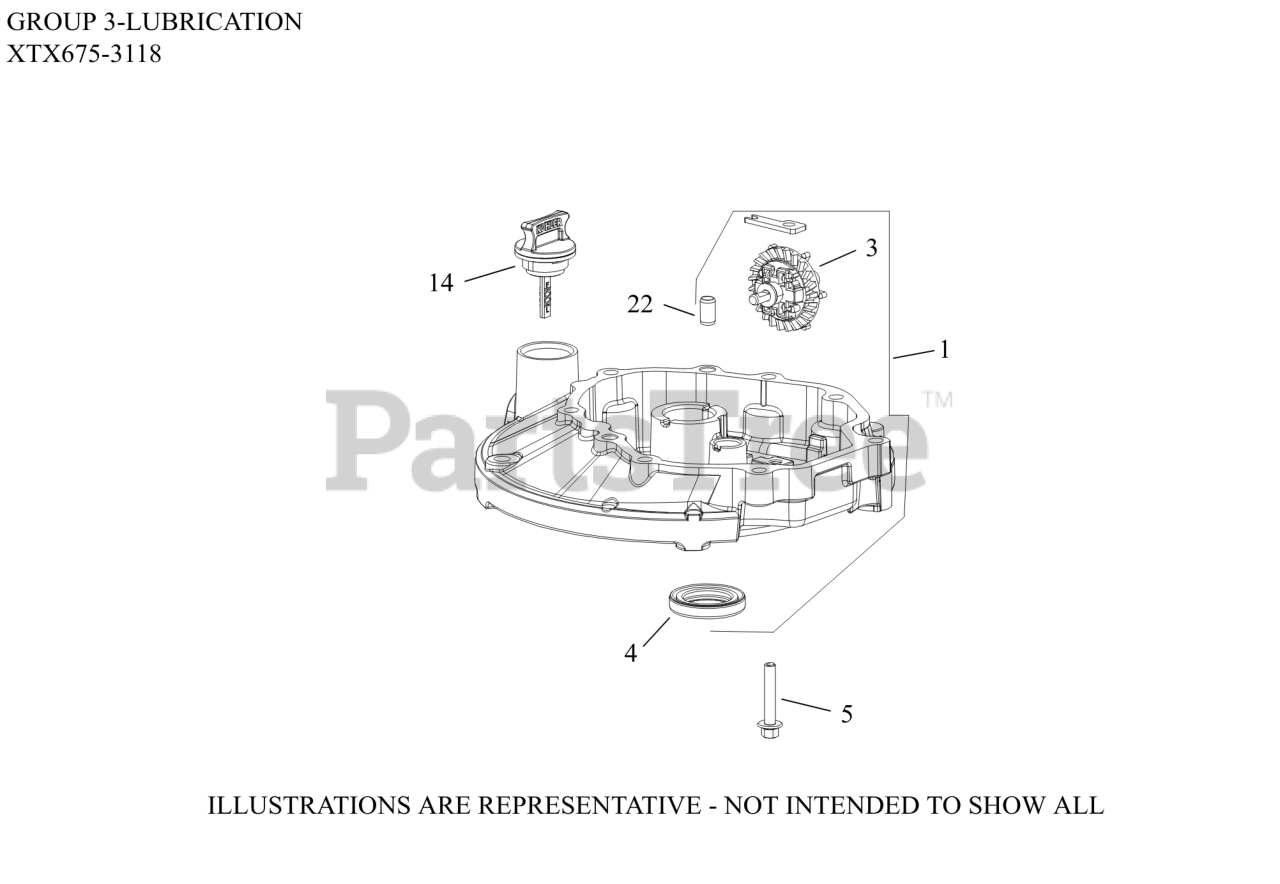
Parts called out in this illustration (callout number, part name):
1	KIT, OIL PAN
3	GEAR ASSEMBLY, GOVERNOR
5	SCREW, HEX FLANGE (M6)-(#25086434S)
14	DIPSTICK ASSEMBLY
22	PIN, DOWEL (8mm)
